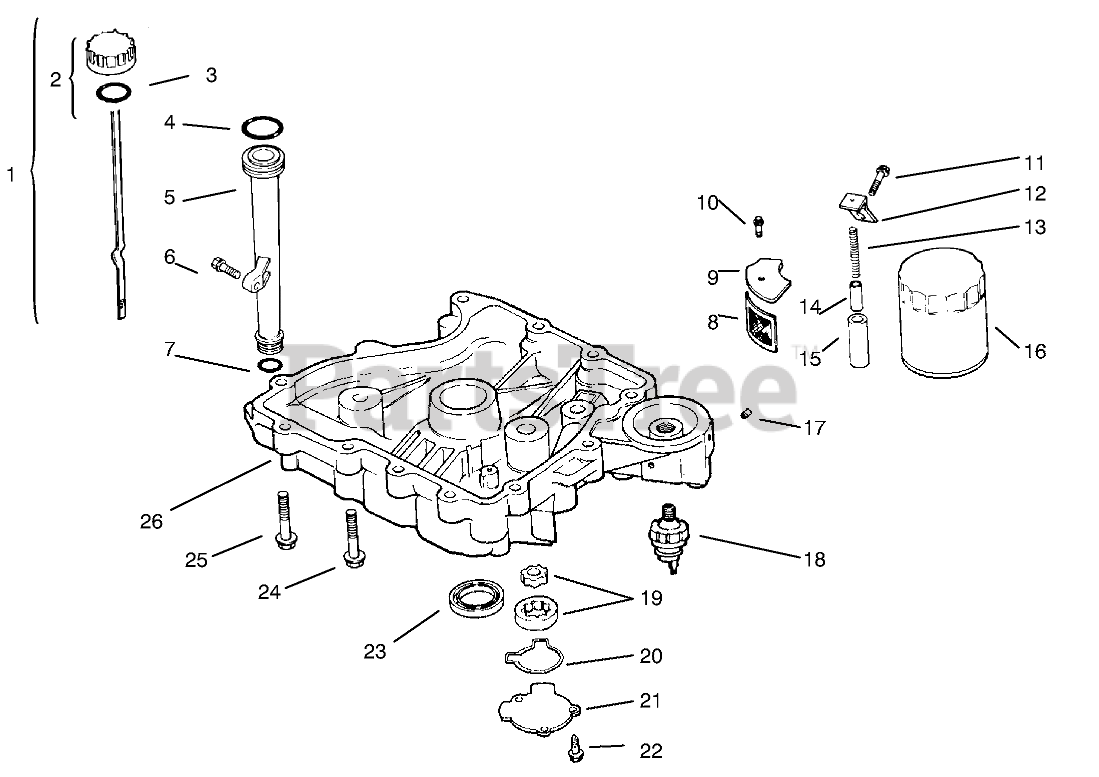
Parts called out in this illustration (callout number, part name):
1	Dipstick INC 2-3
2	Kit-Oil Fill Cap
3	"O"Ring
4	"O"Ring
5	Tube-Oil Fill
6	Screw
7	"O"Ring
8	Screen-Oil Pickup
9	Cover-Oil Screen
10	Screw-HF
11	Screw
12	Bracket-Oil Pump Relief
13	Spring-Oil Relief Valve
14	Piston-Oil Relief Valve
15	Body-Oil Relief Valve
16	Filter-Oil
17	Plug
18	Switch, pressure
19	Pump-Oil
20	"O"Ring-Pump Cover
21	Cover-Oil Pump
22	Screw-HF
23	Seal-Crankshaft
24	Screw
25	Screw
26	Pan-Oil
